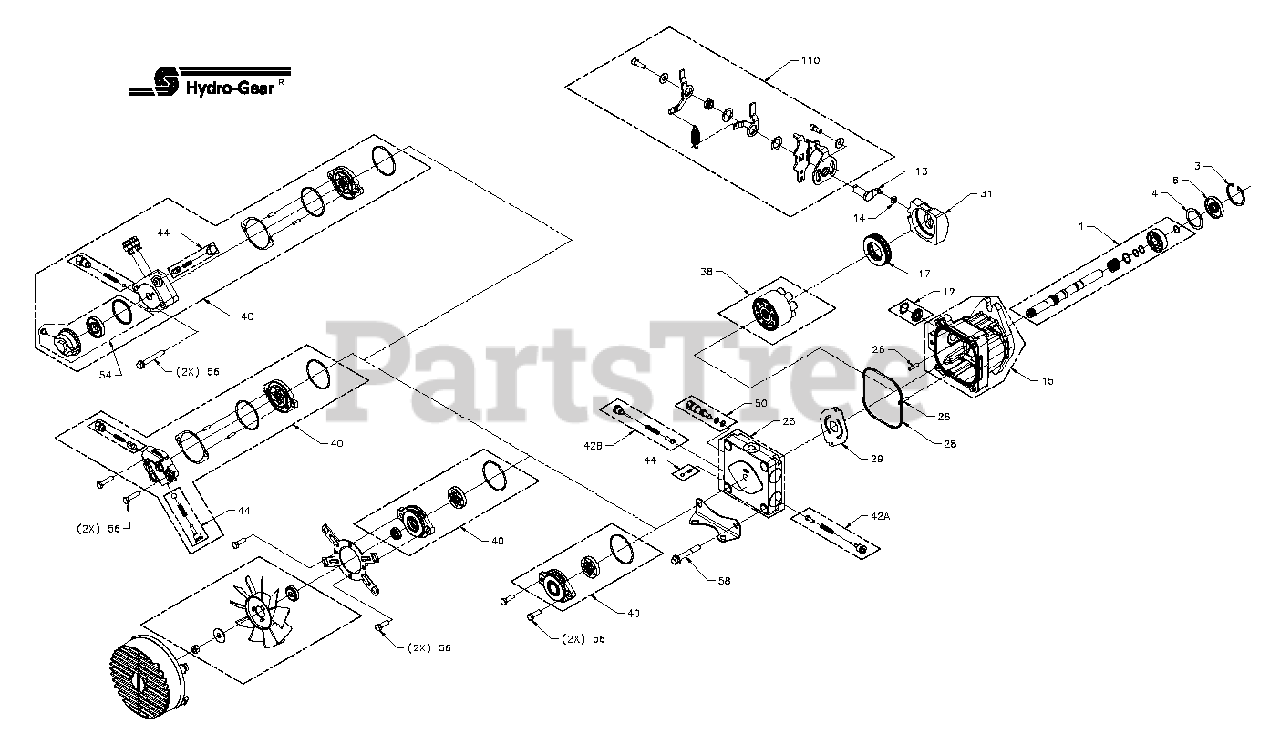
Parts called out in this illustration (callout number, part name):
1	Kit, Pump Shaft
3	Ring, Ret 47 Int
4	Washer, 1.45 x 1.84 x .04
6	Seal, Lip 17 x 47 x 8
12	Kit, BDP-16A Trunnion Seal
13	Arm, Trunnion
14	Guide, Slot
15	Service Kit, Housing
17	Bearing, Thrust Ball 42 x 68 x 16
25	Kit, End Cap
26	Pin, .219 x 1
28	O-Ring, Sq .1 x (4.3 x 4.6)
29	Valve Plate
31	Plate, Swash 21cc
38	Kit, Motor Block
40	Kit, Aux Pump
42	Kit, Shock Valve 200 Bar
44	Kit, Chrg Relief Valve
50	Kit, Bypass Valve
54	Auxilarty Filter Kit
56	HFHCS 5/16-18 x 2.5
58	Kit, Bolt
NS	Kit, Rtn
